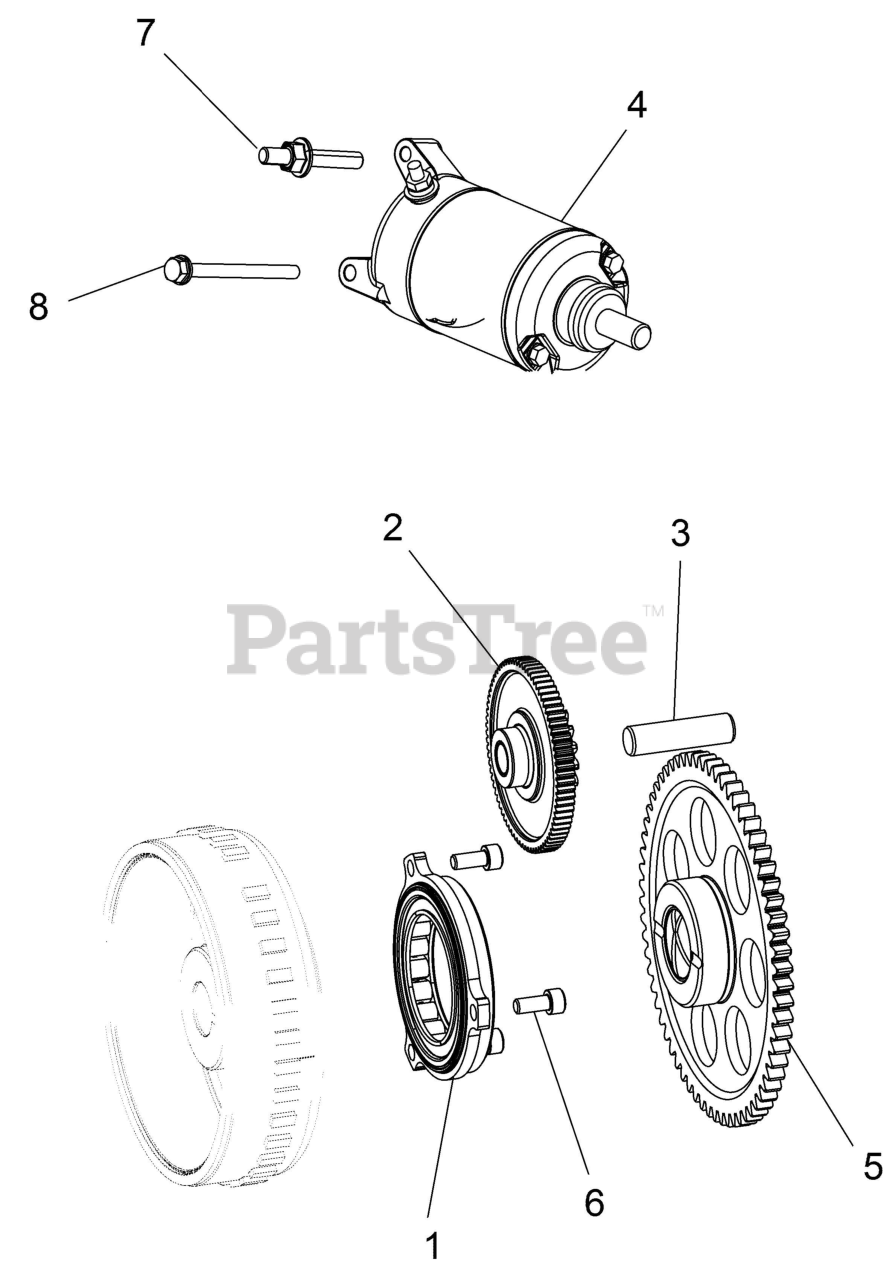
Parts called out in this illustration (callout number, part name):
1	ASM,SPRAG CLUTCH,HUB,STARTER
2	ASM-GEAR,STARTER
3	PIN-SOLID,STARTER TQ LIMITGEAR
4	STARTER, 1 CYLINDER
5	GEAR-FREEWHEEL,1WAY CLUTCH
7	STUD-DOUBLE,END,M6X1.0X25/10
